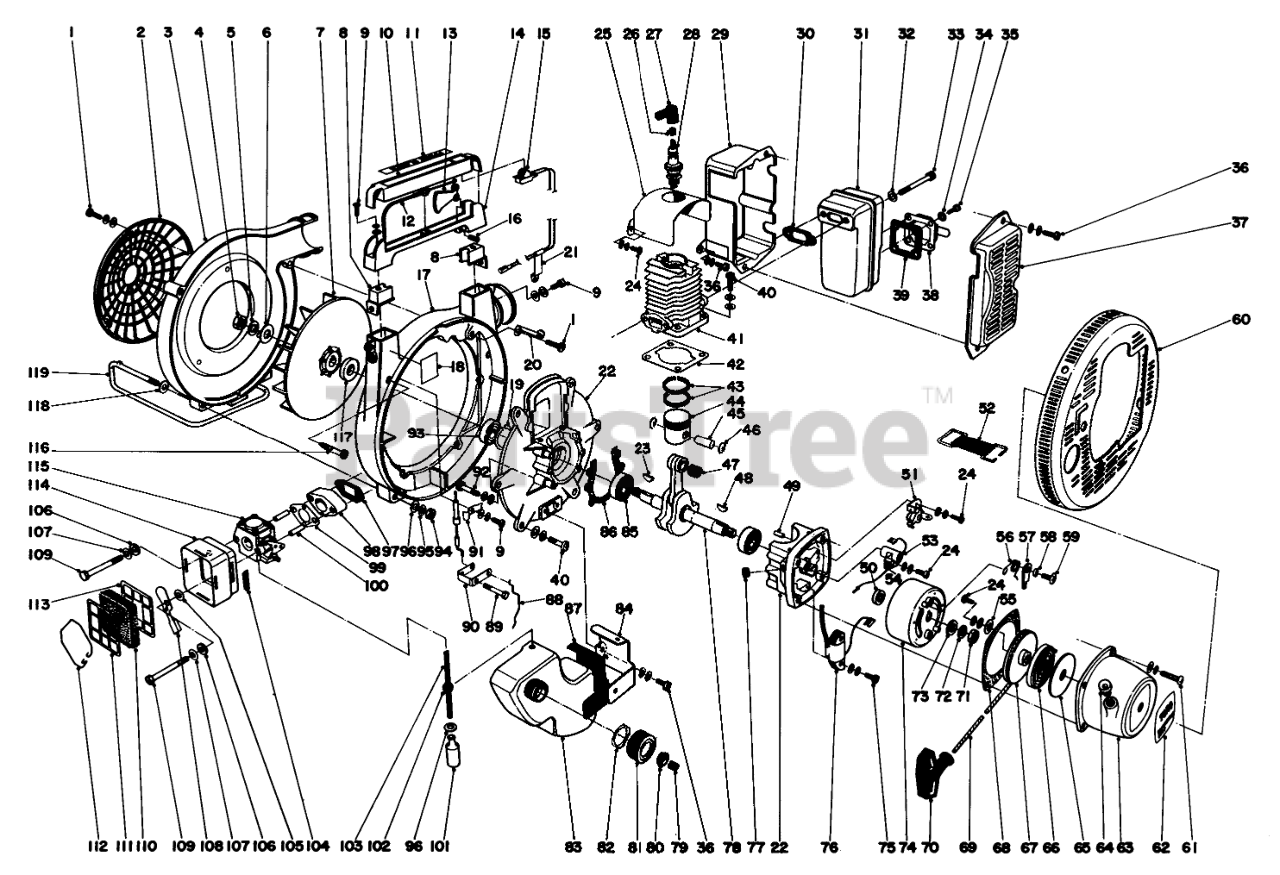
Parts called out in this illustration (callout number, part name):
1	Screw W/washers
2	Grid Fan Casing
3	Fan Case
5	Spring Washer
6	Washer
8	Rubber Cushion
9	SCREW
10	Grip, Right Handle
11	Decal-Power Blower
12	Throttle Cable
13	Throttle Trigger
14	RIGHT HANDLE
15	Stop Switch
16	Spring Pin
17	Fan Case
18	Decal-Choke
19	Circlip
20	Holder, Cover
21	Cord Clip
22	Crankcase Set (Incl. Ref. #49)
23	Woodruff Key
24	SCREW
25	Cylinder Cover
26	Coil Spring-Plug Cap
27	Cap-Spark Plug
28	Spark Plug
29	Muffler Cover
30	Gasket, Muffler
31	Muffler
32	WASHER
34	Washer
35	Screw
36	SCREW
37	Muffler Cover
38	Muffler Lid
39	Gasket, Muffler Lid
40	Screw W/washers
41	Cylinder
42	Gasket, Cylinder Base
43	PISTON RING
44	Piston
45	Piston Pin
46	Circlip, Piston Pin
47	Needle Bearing
48	Woodruff Key
49	Knockpin
50	Oilseal
51	CONTACT BREAKER SET
53	Condenser
54	Oiler
55	Washer
56	Ratchet Spring
57	Ratchet
58	RATCHET SPACER
59	Screw
60	Cover
61	SCREW
62	Decal Commercial Duty
63	Starter Case
64	Rope Guide
65	SIDE PLT
66	REWIND SPRING
67	RECOIL DRUM
68	Gasket, Starter Case
69	Starter Rope
70	Starter Handle
72	Spring Washer
73	Washer
74	Flywheel
75	Screw
76	IGNITION COIL
77	Grommet
78	Crankshaft Assembly
79	Filter
80	Check Valve
81	Fuel Cap Assembly(Incl. Ref. #79, 80, & 82)
82	FUEL TANK CAP GASKET
83	Fuel Tank
84	Retainer, Fuel Tank
85	Bearing
86	Gasket, Crankcase
87	Cushion
88	Throttle Connecting Rod
90	Arm, Throttle Lever
92	Screw
93	Oilseal
95	Washer
96	Washer
97	GASKET
98	Insulator
99	Gasket
100	Carburetor Spacer
101	Fuel Strainer
102	GROMMET
103	Fuel Hose
104	Grommet
105	CHOKE SHUTTER SPACER
106	WASHER
107	Spacer, Carburetor
108	Choke Shutter
110	Air Filter
111	Air Cleaner Grid
112	Spring, Air Cleaner
113	Air Cleaner Grid
114	Case, Air Cleaner (Incl . Ref. #104)
115	Carburetor Assembly
116	Screw
117	Spacer
118	WASHER
119	Stand
